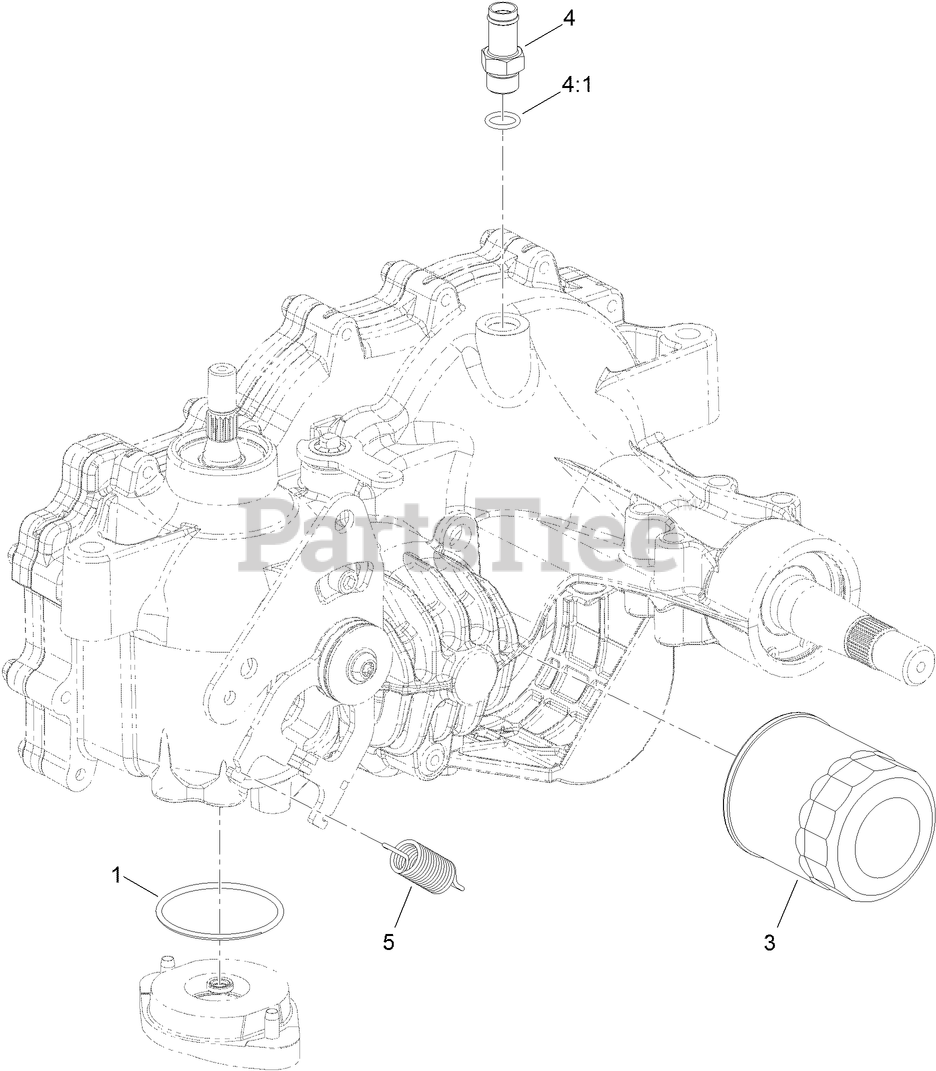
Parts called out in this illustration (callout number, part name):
1	O RING-SEAL
3	ELEMENT-OIL FILTER, HYD
4	ADAPTER-STRAIGHT
4:1	O-Ring
5	SPRING-EXTENSION
